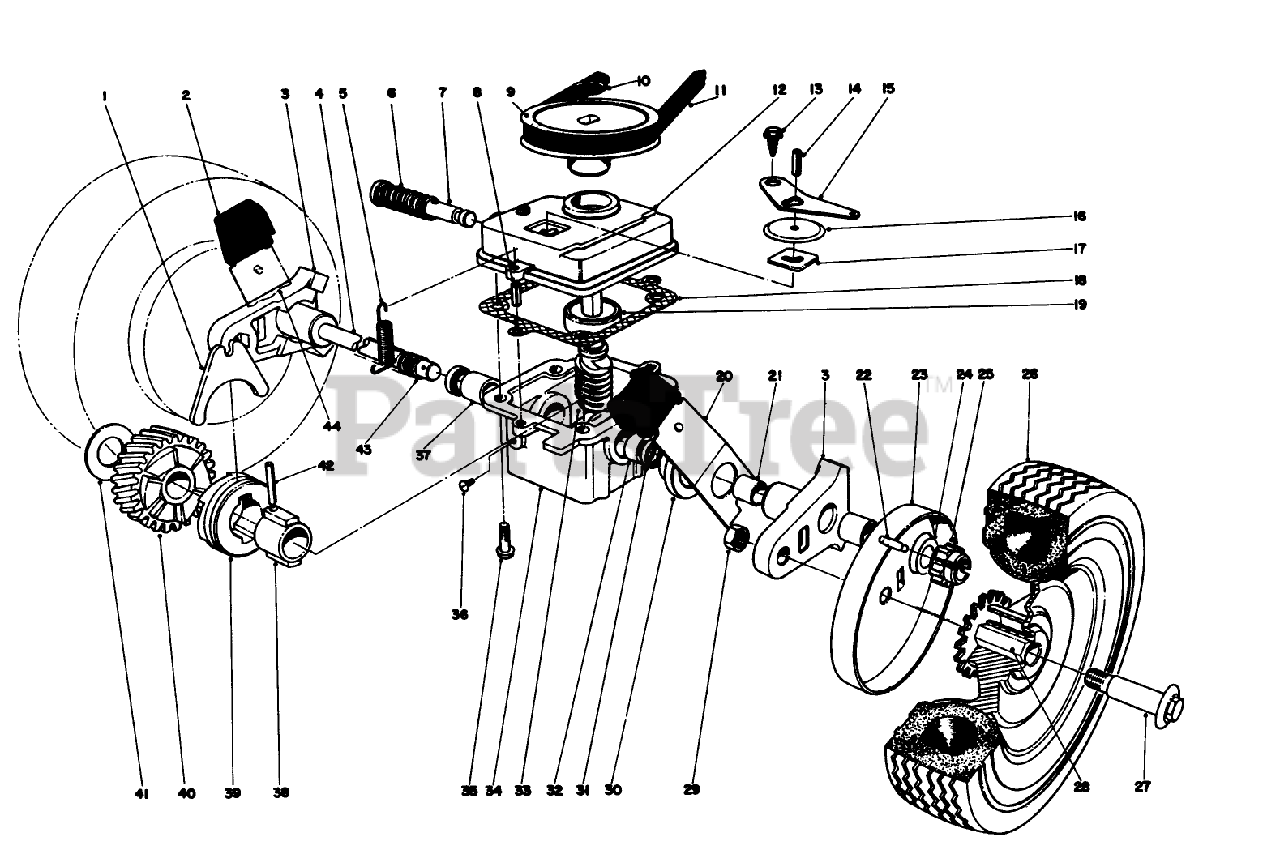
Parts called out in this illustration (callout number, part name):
1	SHIFTER FORK
2	KNOB-ARM
5	TENSION SPRING
6	SPRING
8	3/16 X 1/2 ROLL PIN
10	PUSH-ON 93-3236
11	BELT-V
14	PIN-ROLL
15	SHIFTER ARM
16	TRANS DUST COVER
17	LATCH PLATE
18	GASKET
21	BUSHING
22	PIN-GROOVED
23	Wheel Cover
24	WASHER-THRUST
30	End Cap
32	Bushing
33	WORM SHAFT
36	NYLON SCREW
37	259 Bushing
38	SLEEVE
39	CLUTCH JAW
41	THRUST WASHER
42	COIL PIN
43	COVER-SHAFT, DRIVE
44	SPRING ARM ASM SP RH
